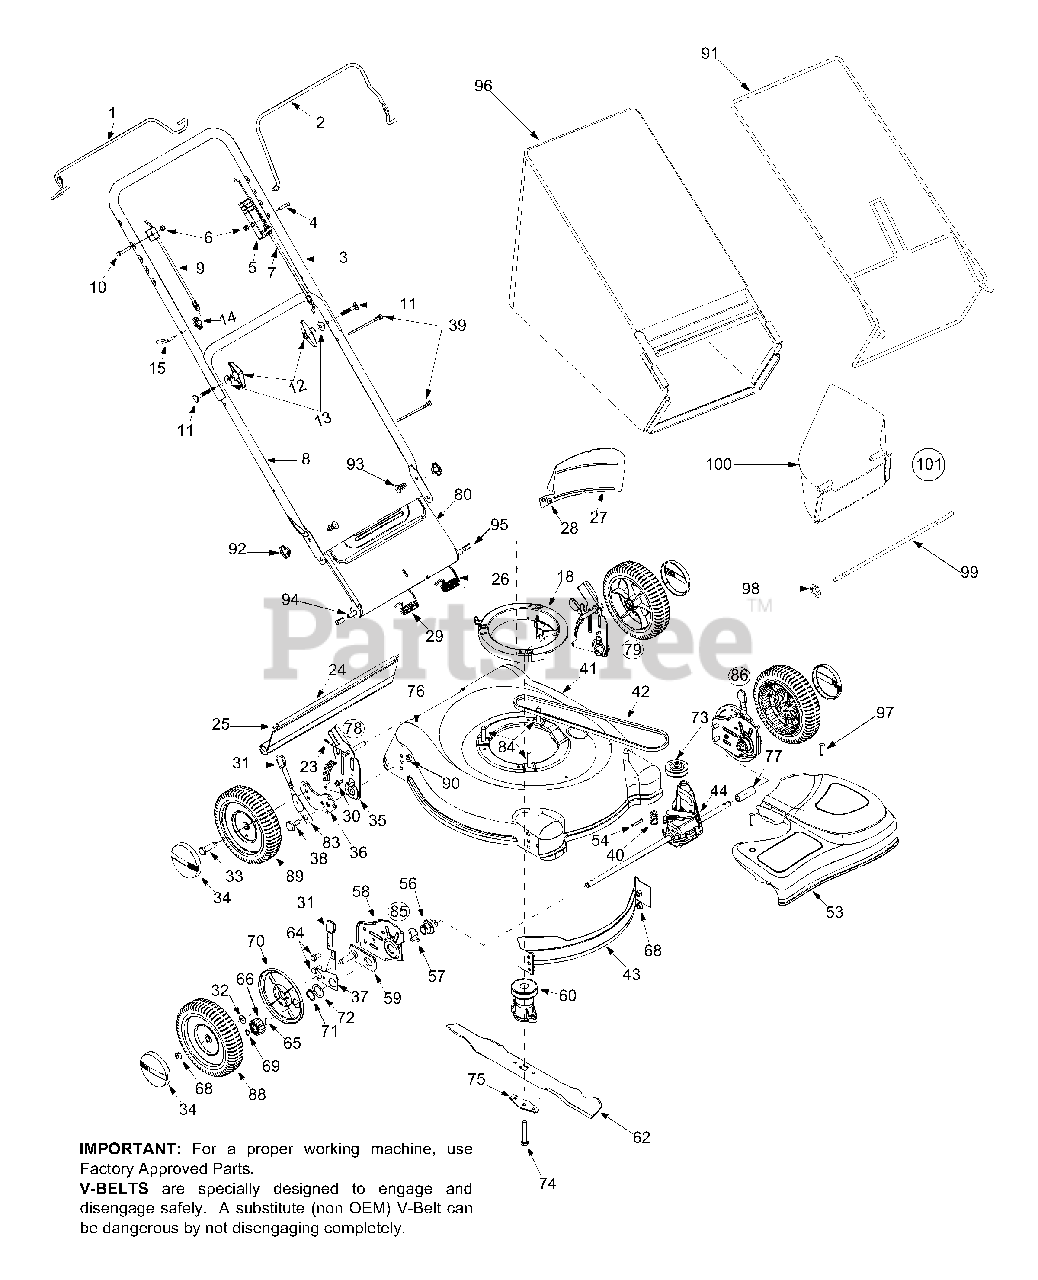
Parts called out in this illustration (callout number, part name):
5	Control Housing
6	Hex Lock Nut 1/4-20
7	Control Cable: 43"
9	Drive Cable
10	Hex Screw 1/4-20 x 1.5"
11	Carriage Bolt
12	Handle Knob
13	Saddle Washer
14	Wing Nut
15	Rope Guide
18	Engine Spacer Assembly
23	Hairpin Clip
24	Rear Trail Shield
25	Wire: Trail Shield
26	Torsion Spring LH
28	Scr. AB 1/4-14 x 0.625"
29	Torsion Spring RH
30	Hex Scr. w/ Wash. 1/4-14 x 0.62"
31	Knob
32	Bell Washer .375 x .870
33	Shoulder Screw
34	Hubcap
37	Front Lever RH
38	Shoulder Screw
39	Cable Tie
40	Belt Tension Spring
41	Rear Discharge Deck: 21"
42	V-Belt
53	Front Drive Cover
54	Roll Pin
56	Bearing Assembly
57	Wave Washer
60	21" One Piece Blade Adapter
62	Mulching Blade w/ Star: 21"
64	Hex Screw
65	Dowel Pin
66	Gear 14T RH
68	Hex Nut
69	Snap Ring
70	Wheel Dust Cap
71	Snap Ring
72	Washer DD 1.5" O.D.
73	Input Pulley
74	Hex Bolt
75	Bell Blade Support
77	Slev. Spacer LH
78	Handle Brkt Assembly RH Compl.
79	Handle Brkt Assembly LH Compl.
80	RD Chute Door
83	Spring Lever
84	TT Screw
85	Height Adj. Assembly RH Compl.
86	Height Adj. Assembly LH Compl.
88	Front Wheel Complete, 8x1.8
89	Rear Wheel Complete, 8X1.75
90	Hex Nut
92	Wing Nut
93	Hex Carriage Screw
94	Rear Door Pivot Rod
95	Spacer .390OD x .810ID x .950"
96	Grass Bag
97	Shoulder Screw
98	Nut: Spd. 3125 ID
99	Rod
100	Side Discharge Adapter
101	Chute Deflector Complete
